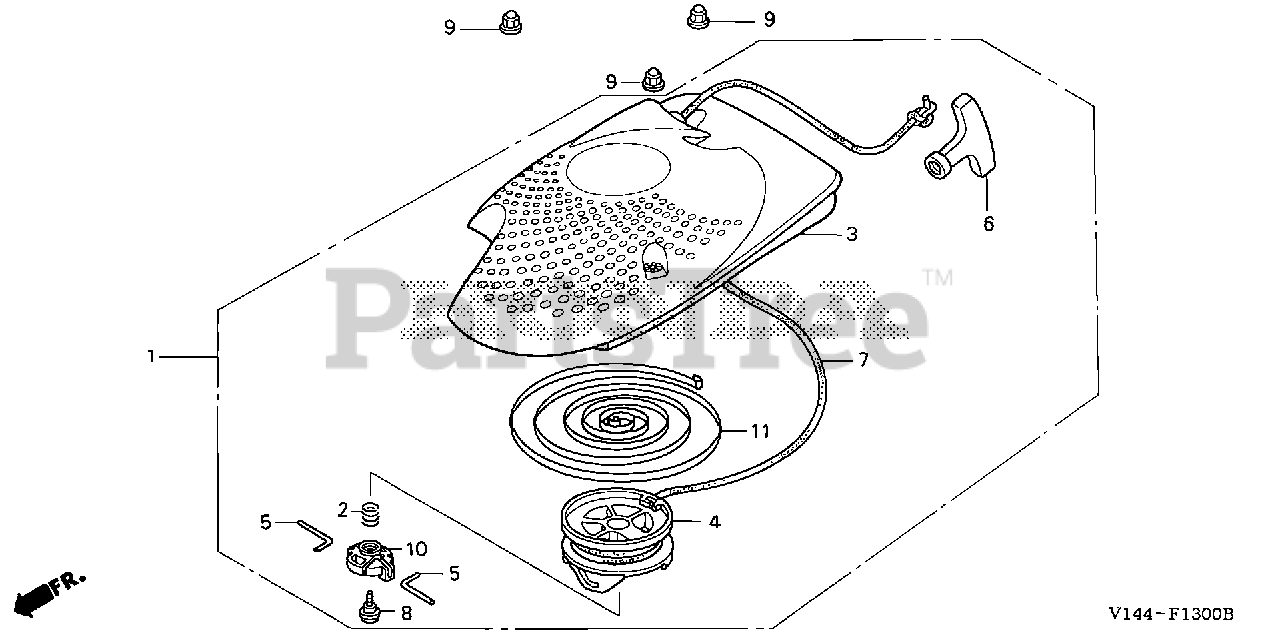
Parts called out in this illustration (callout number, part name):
1	STARTER ASSY., RECOIL *R280* (POWER RED)
2	SPRING, FRICTION
3	CASE, STARTER *R280* (POWER RED)
4	REEL, RECOIL STARTER
6	GRIP, STARTER
6	KNOB, RECOIL SRARTER
7	ROPE, RECOIL STARTER
8	SCREW, SETTING
9	NUT, FLANGE CAP (5MM)
11	SPRING, RECOIL STARTER
